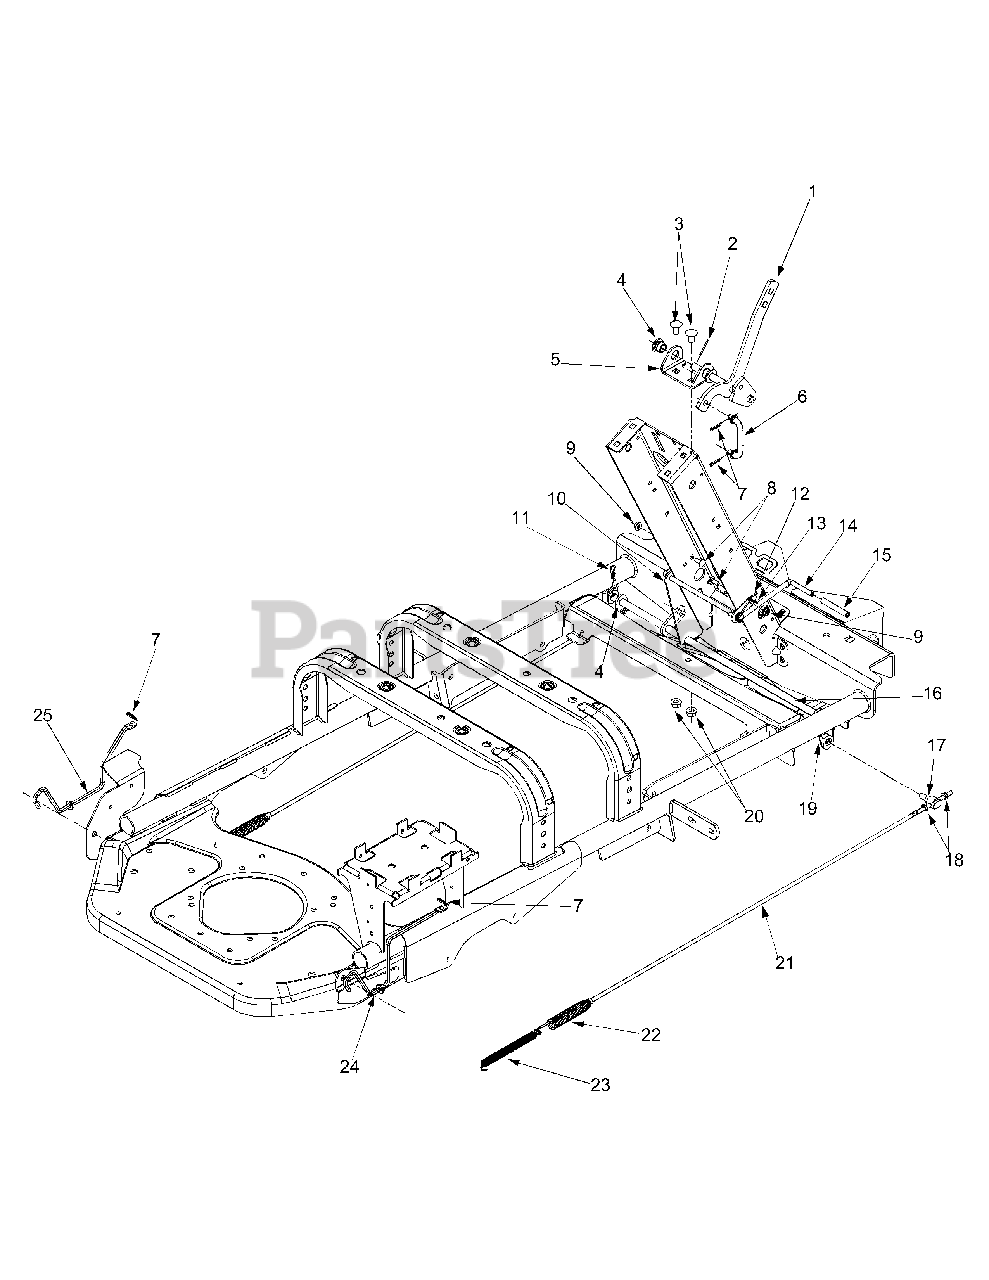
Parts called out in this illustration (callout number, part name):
1	Parking Brake Shift Ass’y
3	Carriage Bolt 3/8-16 x .75
4	Hex Flange Bearing .506 ID x .590
5	Brake Mounting Bracket
6	Connecting Brake Rod
8	Carriage Screw 1/4-20 x .62
9	Hex Flange Lock Nut 1/4-20
10	Support Plate
12	Retaining Rod Bracket
13	Torsion Spring 5/16
14	Parking Brake Retaining Rod
15	Parking Brake Pad
16	Brake Rod Ass’y
18	Jam Nut 1/4-28
19	Flat Washer .385 ID x 1.0 OD
20	Flange Lock Nut 3/8-16
22	Extension Spring
23	Extension Spring
24	Release Pump Rod RH
25	Release Pump Rod LH
